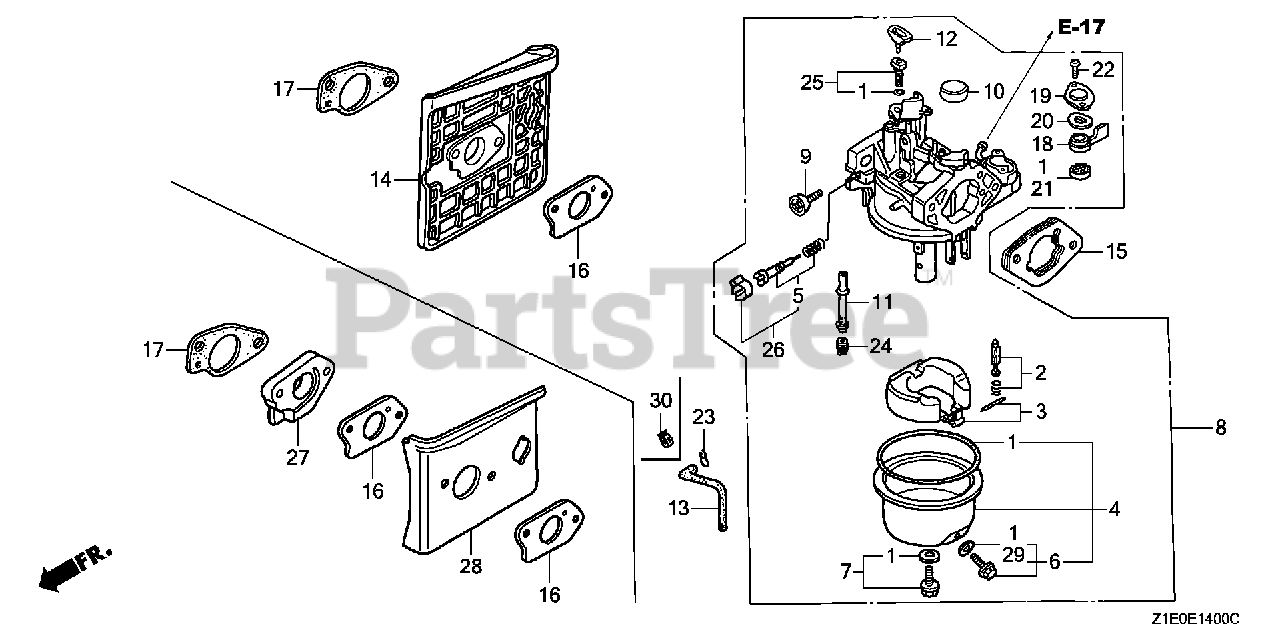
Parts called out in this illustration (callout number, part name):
1	GASKET SET (EXC. 16173-001-004) (CARBURETOR NO.) (EXCEPT 16173-001-004)
2	VALVE SET, FLOAT
3	FLOAT SET (CARBURETOR NO.)
4	CHAMBER SET, FLOAT
6	SCREW SET, DRAIN (Honda Code 1672187). (CARBURETOR NO.)
7	SCREW SET
8	CARBURETOR ASSY. (BE86W A)
9	SCREW, THROTTLE STOP
10	CAP, CHOKE LEVER DUST
11	NOZZLE, MAIN (CARBURETOR NO.)
12	COLLAR, SET
13	TUBE, AIR VENT (75MM)
14	INSULATOR, CARBURETOR
15	SPACER, CARBURETOR
16	GASKET, CARBURETOR
17	GASKET, INSULATOR
18	LEVER, VALVE
19	PLATE, LEVER SETTING (CARBURETOR NO.)
20	SPRING, PETCOCK LEVER (CARBURETOR NO.)
21	GASKET, VALVE
22	SCREW, PAN (3X6)
23	CLIP, TUBE (B8)
24	JET, MAIN (#90) Use from Engine SN BE81B C.
24	JET, MAIN (#92)
24	JET, MAIN (#95)
25	JET SET, PILOT (#40) (ADVENTURE GREEN) (CARBURETOR NO.)
26	SCREW SET (CARBURETOR NO.)
29	WASHER, PLAIN (6.2X10.7 DRAIN) (CARBURETOR NO.)
